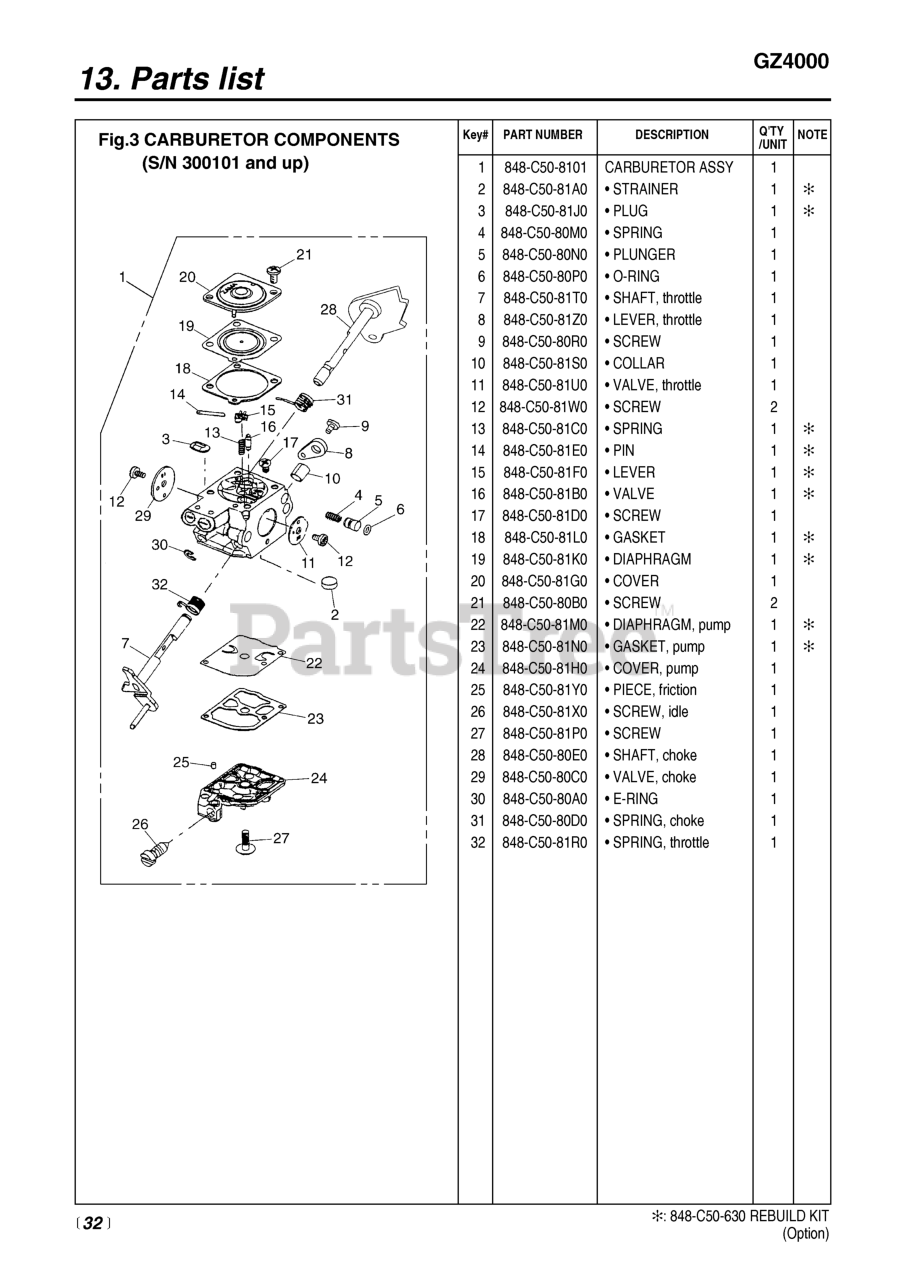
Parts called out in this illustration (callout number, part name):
1	CARBURETOR-ASSY
2	STRAINER
3	PLUG
4	SPRING
5	PLUNGER
6	O-RING
7	SHAFT
8	LEVER
9	SCREW
10	COLLAR
11	VALVE
12	SCREW
13	SPRING
14	PIN
15	LEVER
16	VALVE
17	SCREW
18	GASKET
19	DIAPHRAGM
20	COVER
21	SCREW
22	DIAPHRAGM
23	GASKET
24	COVER
25	PIECE
26	SCREW
27	SCREW
28	SHAFT
29	VALVE
30	E-RING
31	SPRING
32	SPRING
NI	REBUILD KIT
